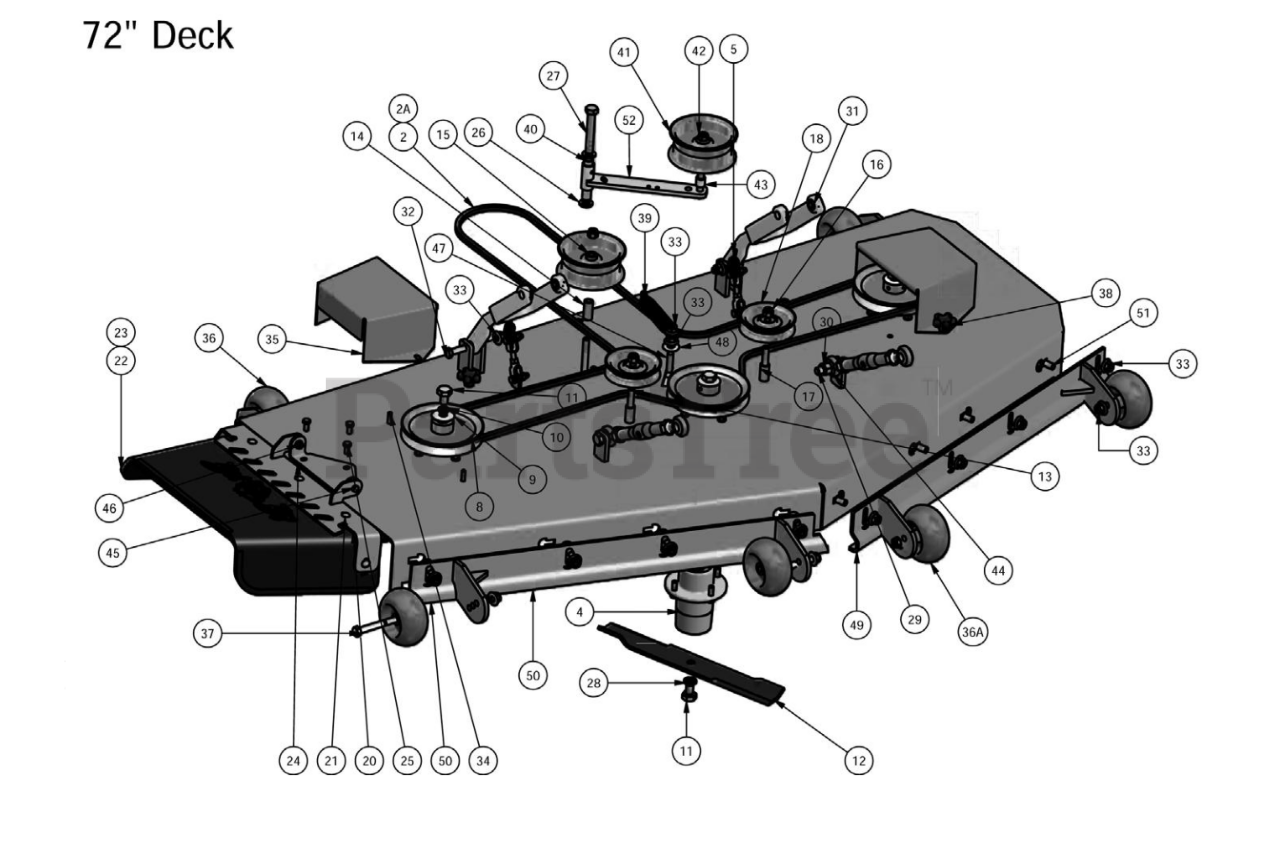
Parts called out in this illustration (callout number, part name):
1	72" Deck Shell
1A	Complete 72" Deck
2	72" Deck Belt (Diesel)
2A	72" Deck Belt (AOS)
3	4 Link Chain Assembly
4	Double Bearing Spindle
5	3/8" x 1 1/4" Hex Bolt
6	3/8" Lock Washer
7	3/8-16 Hex Nuts Zinc
8	7" Deck Pulley
9	Cup Washer
9A	5/16" Set Screw
10	1/2" Lock Washer
11	5/8" x 1 1/2" Hex Bolt Grade 8
12	72" Fusion High Lift Blade
13	1/2" x 3 1/2" Grade 8 Bolt
14	1 3/4" Pulley Spacer
15	5 3/4" Deck Idler Pulley
16	1/2" Nylock Nut
17	1 1/2" Diesel Pulley Spacer
18	4 3/4" Idler Pulley
19	72" Lower Hanger
20	72" Discharge Chute Upper Hanger Plate
21	5/16" x 1 1/4" Carriage Bolt
22	Rubber Discharge Chute
23	72" Complete Chute Assembly
24	Discharge Chute Hanger (deck mounted)
25	3/8" x 3/4" Hex Bolt
26	.635 ID Plastic Washer
27	5/8" x 4" Hex Bolt
28	5/8" Lock Washer
29	5/8" x 2 1/2" Hex Bolt
30	5/8 Std NC Nylock Nut
31	Deck Arm Assembly
32	1/2" x 2 1/2" Hex Bolt
33	1/2 Nylon Flange Nut-Orange
34	5/16" x 1 1/4" Hex Bolt
35	72" Pulley Cover
36	Anti-Scalp Rollers
36A	Complete Roller Assembly
37	1/2" x 4" Bolt (Grade 8)
38	5/16" Knob
39	Deck Idler Spring 2009
40	5/8 x 1 1/8 Brass Bushing
41	5 3/4" Deck Idler Pulley
42	1/2-13 Nylon Flange Nut-Orange
43	3/4 OD x 1/2 ID x 3\4 Length
44	Turnbuckle (Top Link)
45	5/16" x 1" Hex Bolt
46	5/16" Nylock Flange Nut
47	1/2 x 2" Carriage Bolt
48	1/2" Flat Washer
49	72" Deck Adjustable Front (Left)
50	72" Deck Adustable Front (Right)
51	1/2" x 1 1/4 Carriage Bolt
52	Deck Idler
